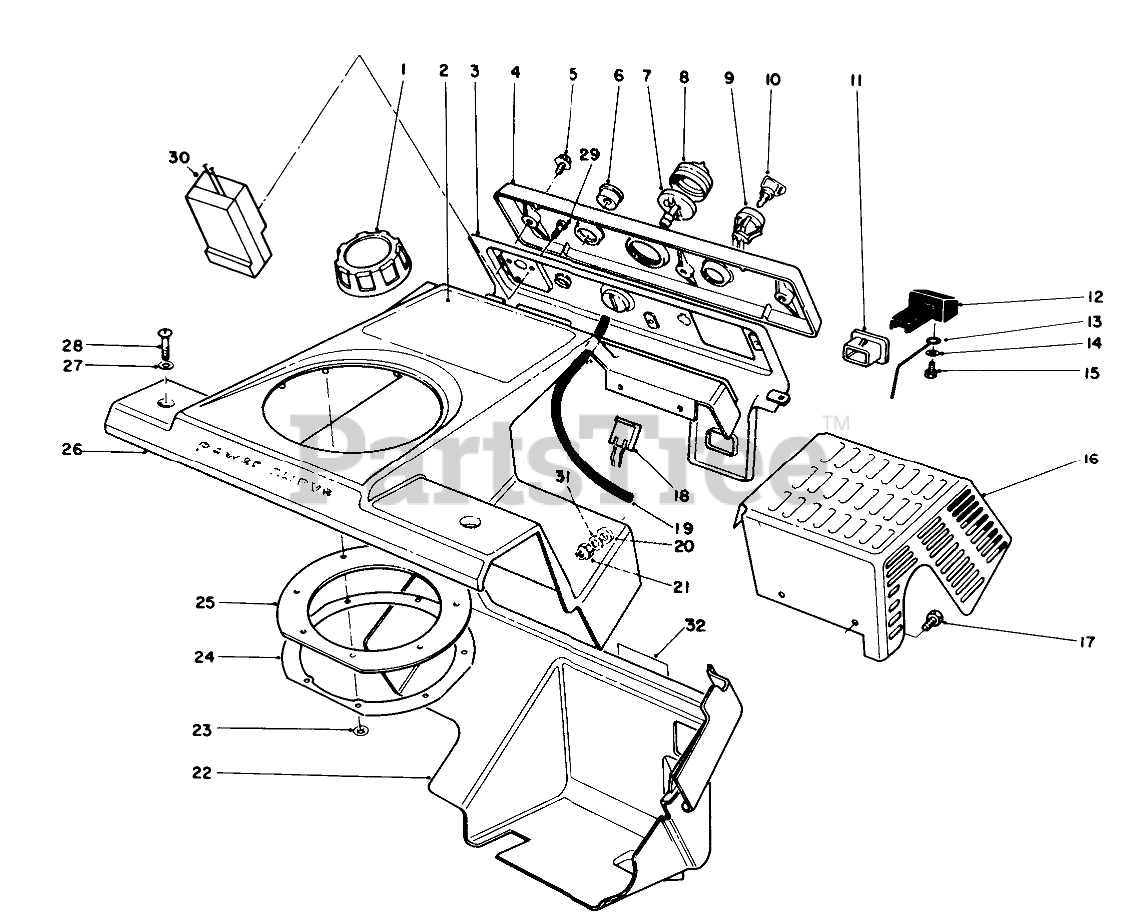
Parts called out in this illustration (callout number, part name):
1	CAP-FUEL ASM
2	DECAL - CCR 2000E
3	Panel-Control (Incl. Ref. #6-8 & 11)
4	Plate-Name
5	SCREW-HWH
6	GUIDE-ROPE, STARTER
7	BODY-PRIMER
8	BULB-PRIMER
9	SWITCH
10	KEY-IGNITION
11	FITTING
12	CONTROL-CHOKE
13	Unkage-Choke
14	WASHER-PLAIN
15	SCREW-PPH
16	Wa-Shield
17	SCREW-SHH
18	CONNECTOR-BODY
19	PRIMER HOSE
20	WASHER
21	NUT-LOCK, NI
22	LOWER SHROUD
23	PALNUT
24	Retainer-Chute Seal
25	SEAL-CHUTE
26	Upper Shroud Assembly (Incl. Ref. #2 & 23-25)
27	WASHER-FLAT
28	SCREW-PPH
29	SCREW-PLASTITE
30	Switch Assembly
31	WASHER-FLAT
32	DECAL
